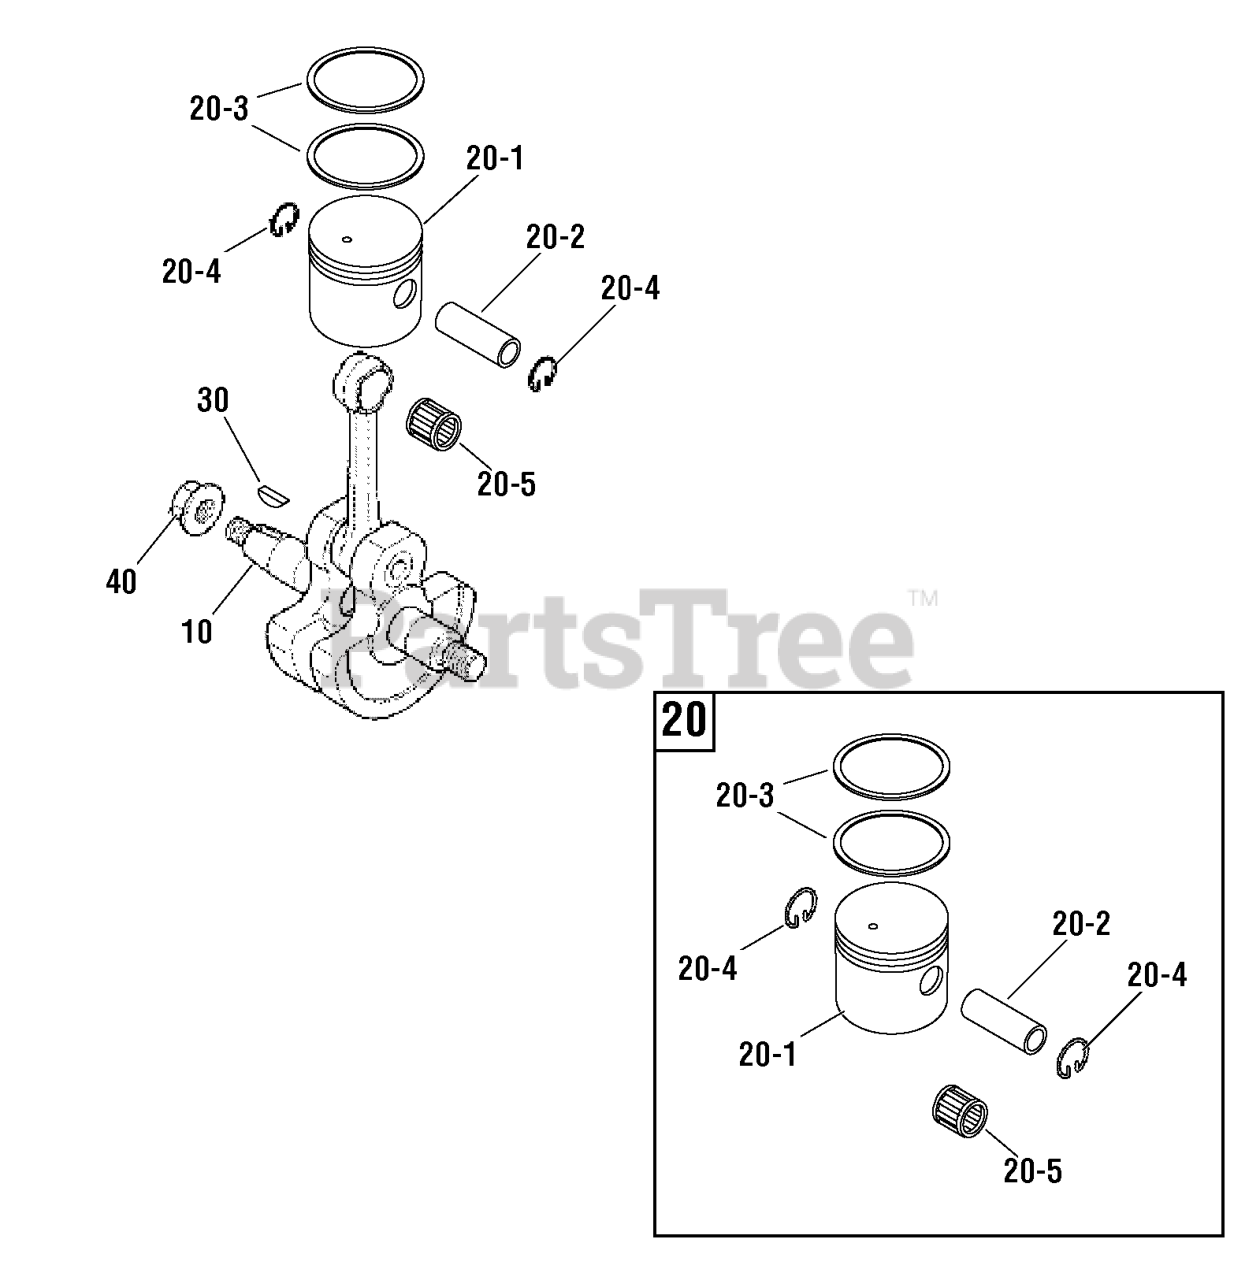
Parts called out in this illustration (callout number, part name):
10	CRANKSHAFT ASSEMBLY
20	PISTON & RING ASSEMBLY
20-1	PISTON
20-2	PIN, Piston
20-3	RING, Top
20-4	CLIP, Piston Pin
20-5	BEARING, Needle
30	KEY, Woodruff
40	NUT
